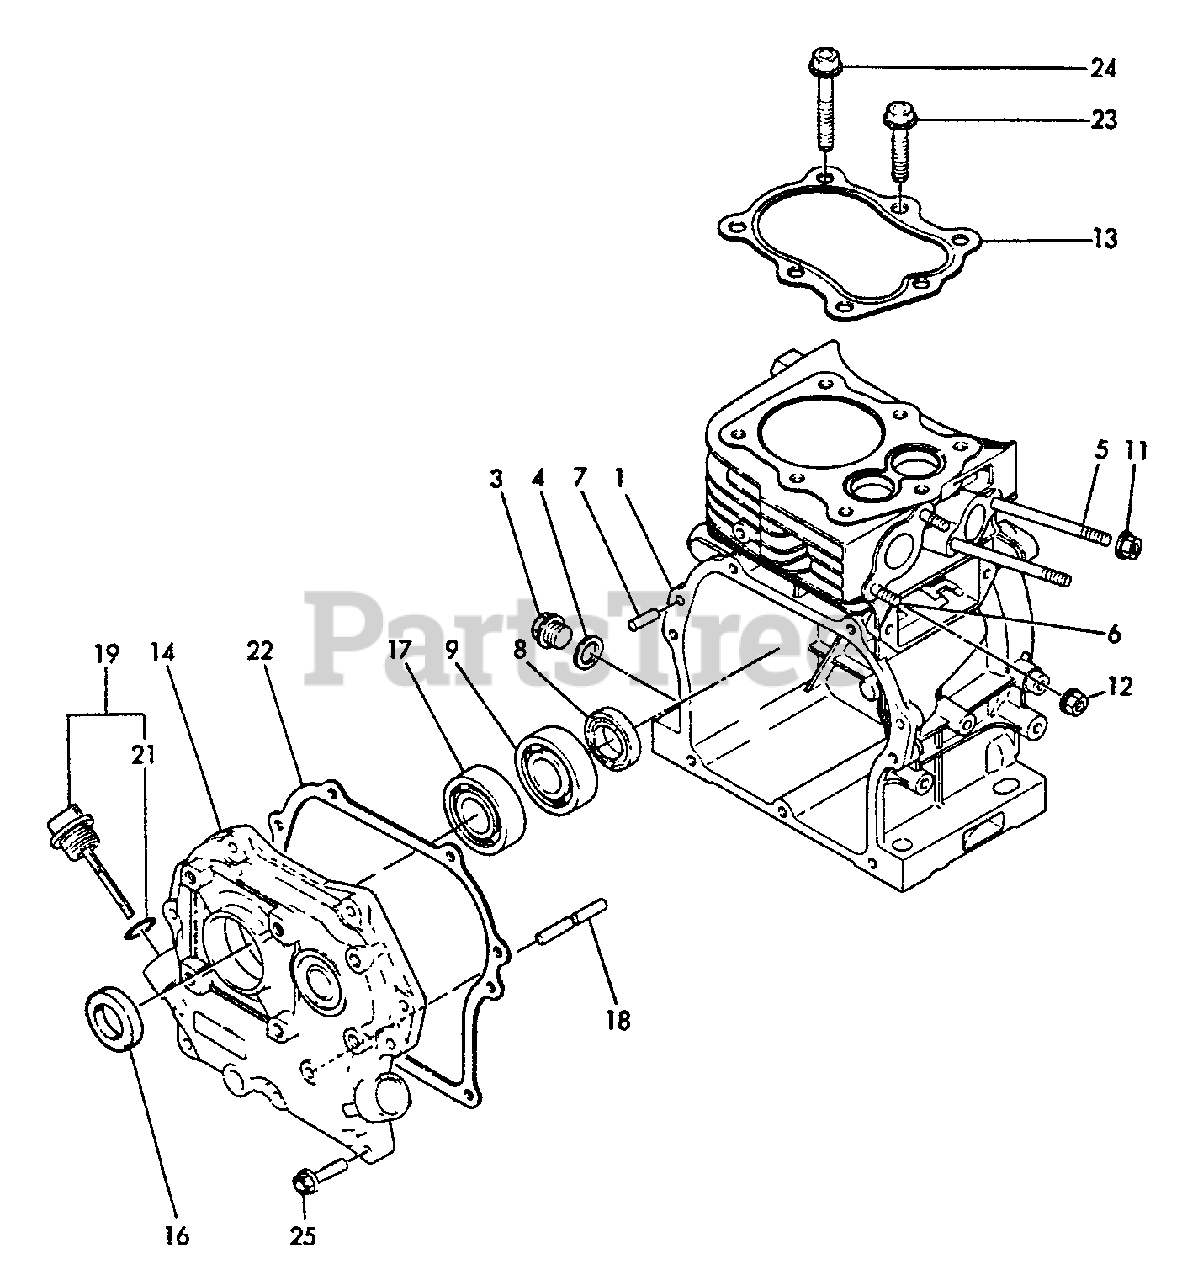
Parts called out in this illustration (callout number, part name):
1	CYLINDER BLOCK SET
3	PLUG, DRAIN
4	GASKET
5	BOLT - 6×70
6	BOLT - 6×16
7	PARALLEL PIN 6×16
8	SEAL, OIL
9	BEARING, BALL 6204 C3
11	U-NUT M6
12	U-NUT M6
13	GASKET, CYLINDER
14	SIDE COVER ASSY
16	SEAL, OIL
17	BEARING, BALL 6204C3
18	SHAFT, GOVERNOR
19	CAP ASSY
21	O-RING 1A P-15.0
22	GASKET
23	BOLT - 8×39
24	BOLT - 8×60
25	BOLT - 6×30
